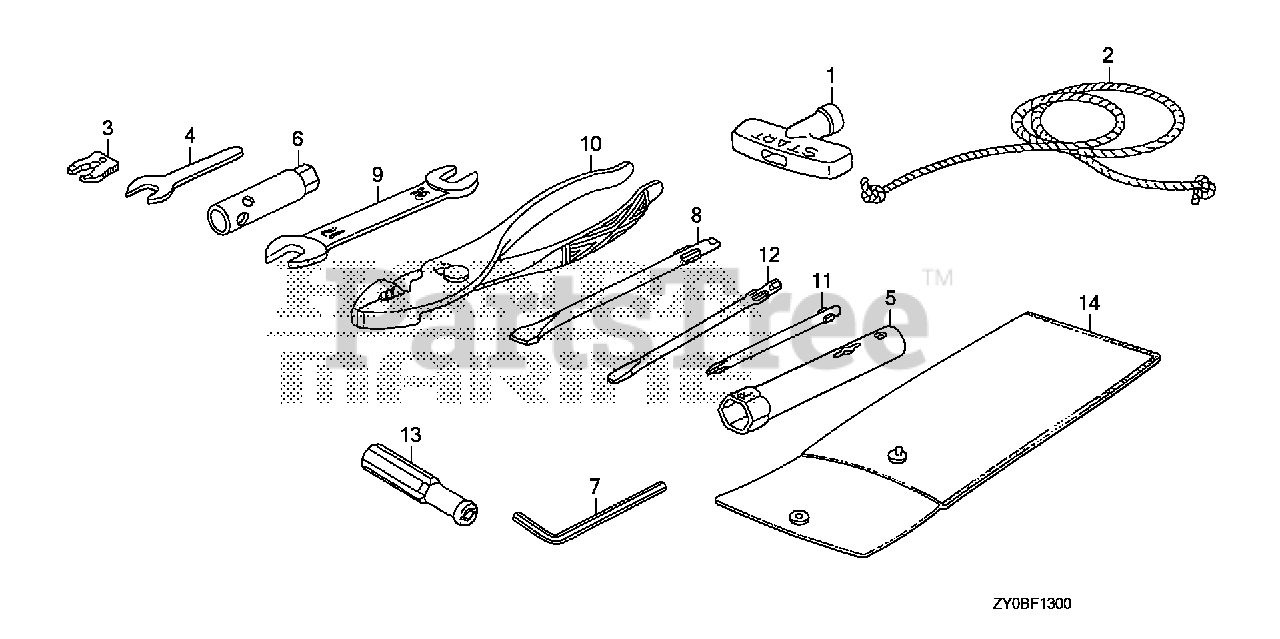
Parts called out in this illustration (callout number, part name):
1	GRIP, STARTER
1	KNOB, RECOIL SRARTER
2	ROPE, RECOIL STARTER (1300MM)
3	CLIP, EMERGENCY LOCK
4	SPANNER (8MM) (NOT AVAILABLE)
5	WRENCH, SPARK PLUG
6	WRENCH, BOX (10MM)
7	WRENCH, HEX. (4MM)
8	SCREWDRIVER, CHECK BOLT
9	SPANNER (10X12)
10	PLIERS (135) (RIKEN)
10	PLIERS (135) (KOWA)
10	PLIERS (135)
11	DRIVER 1, PLUS SCREW (NO.2)
12	DRIVER 3, MINUS SCREW (NO.2)
13	GRIP, SCREW DRIVER
14	BAG, TOOL (160MM)
